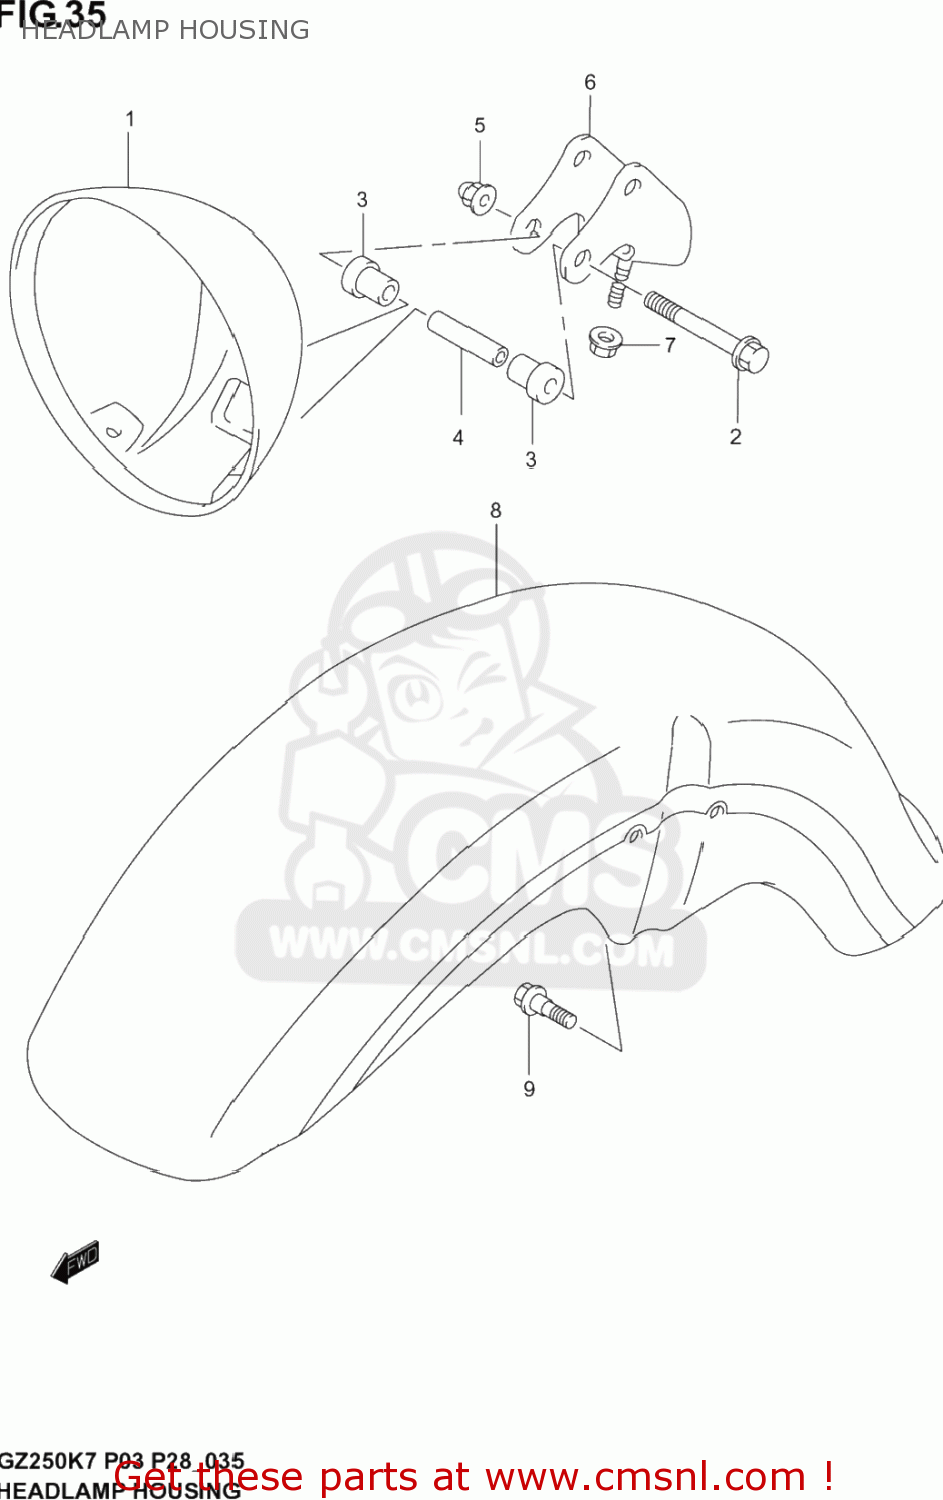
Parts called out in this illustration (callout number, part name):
1	HEADLAMPHOUSIN
2	BOLT
3	CUSHION,HEADLAMP HOUSING
4	SPACER(6.5X9X38.3)
5	NUT
6	BRACKET,HEADLAMP HOUSING
7	NUT
8	FENDER,FR
9	BOLT(6X16)
